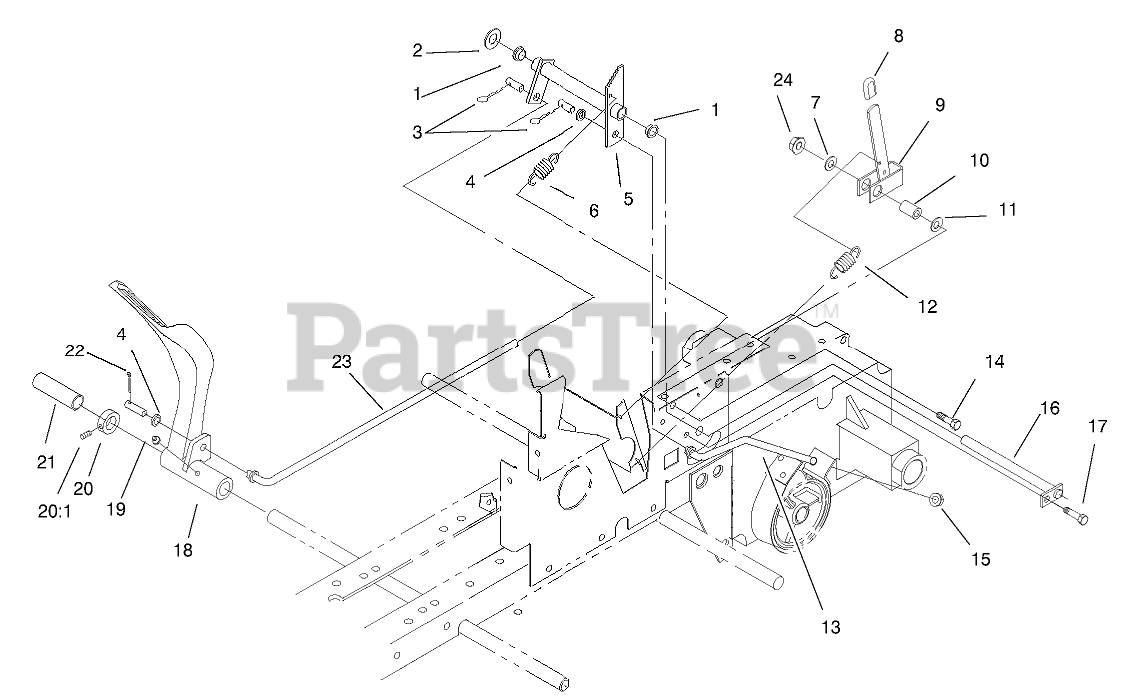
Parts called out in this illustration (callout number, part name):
1	BUSHING-FLANGED
2	WASHER-FLAT
3	PIN-HAIR
4	WASHER-NYLON
5	BELCRANK ASM
6	SPRING-EXTENSION
7	WASHER-FLAT
8	GRIP
9	BRAKE LEVER ASM
10	SPACER
11	WASHER-FLAT
12	SPRING-BRAKE
13	ROD-REAR BRAKE
14	SCREW-HH
15	NUT-LOCK, NI
16	ROD ASM
17	SCREW-HWHTF
18	PEDAL-BRAKE, GEAR
19	FITTING-GREASE
20	COLLAR
20:1	SCREW-HSH
21	SLEEVE-PROTECTIVE
22	PIN-COTTER
23	ROD-BRAKE
24	NUT-LOCK, NI
